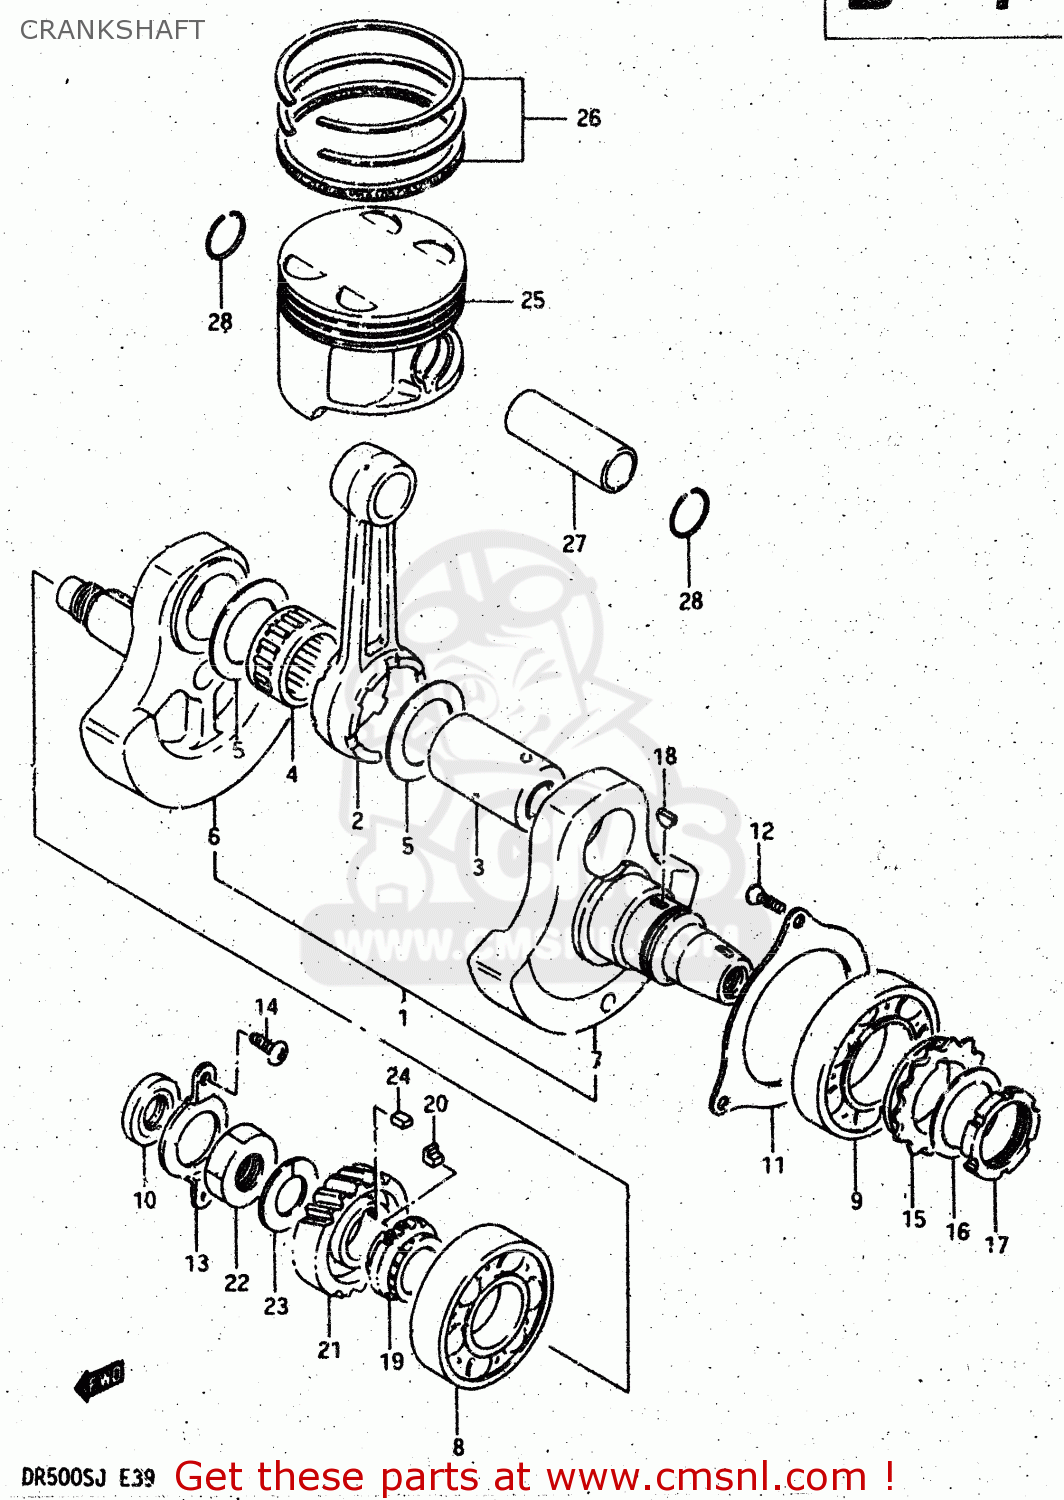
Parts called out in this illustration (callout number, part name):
1	CRANKSHAFT ASSY
2	ROD, CONNECTING
3	PIN,CRANK
4	BEARING
5	WASHER(37X55X1)
6	CRANKSHAFT, RH
7	CRANKSHAFT, LH
8	BEARING(35X80X21)
9	BEARING
10	SEAL,OIL(16X30X6)
11	RETAINER,CRANKSHAFT BEARING,L
12	SCREW
13	RETAINER,CRANKSHAFT BEARING,R
14	SCREW
15	SPROCKET,BALANCER DRIVE
16	WASHER
17	NUT,FLYWHEEL
18	KEY
19	SPROCKET,CAM CHAIN DRIVE
20	KEY,SPROCKET
21	GEAR,PRIMARY DRIVE
22	NUT (20MM)
23	WASHER
24	KEY
25	PISTON
26	RING SET,PISTON
27	PIN,PISTON
28	CIRCLIP
